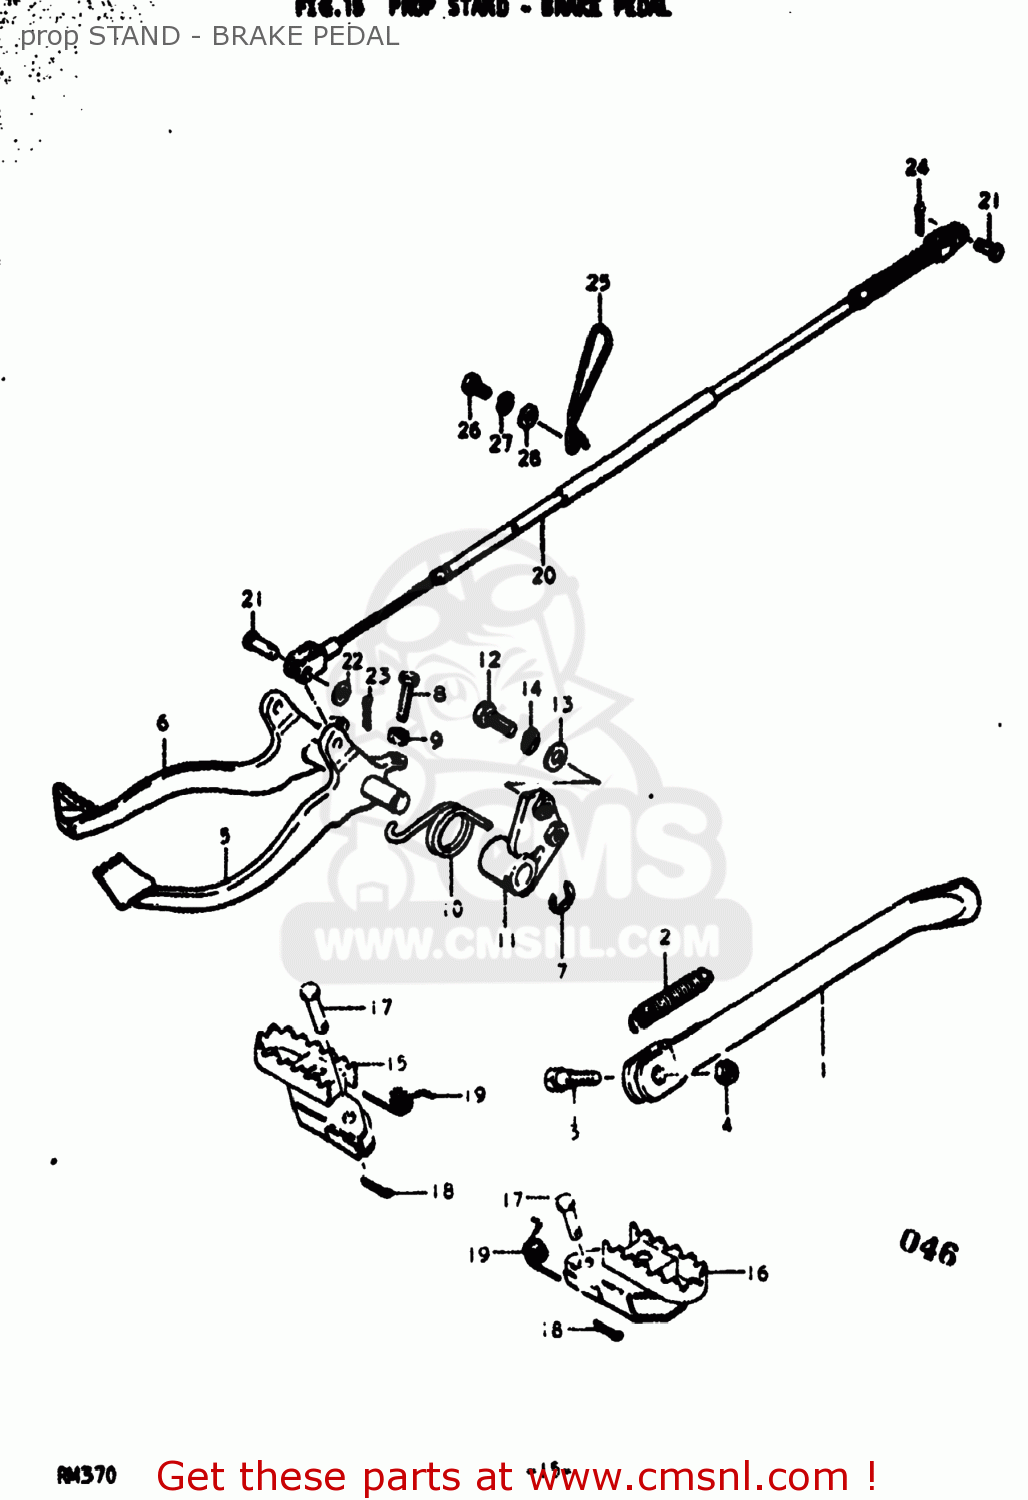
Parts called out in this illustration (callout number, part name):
1	STAND,PROP
2	SPRING
3	BOLT(10X30)
4	NUT
5	PEDAL,BRAKE
6	PEDAL,BRAKE
7	E RING
8	BOLT(6X23)
9	NUT
10	SPRING
11	VALVE ASSEMBLY,WHEEL RIM
12	BOLT
13	WASHER
14	LOCK WASHER
15	BAR,FOOTREST,RIGHT
16	FOOTREST
17	PIN
18	PIN 20X20
19	SPRING
20	CABLE ASSEMBLY,REAR BRAKE
21	PIN(L:17.5)
22	WASHER
23	PIN 20X20
24	PIN
25	GUIDE,CABLE
26	BOLT
27	LOCK WASHER
28	WASHER
